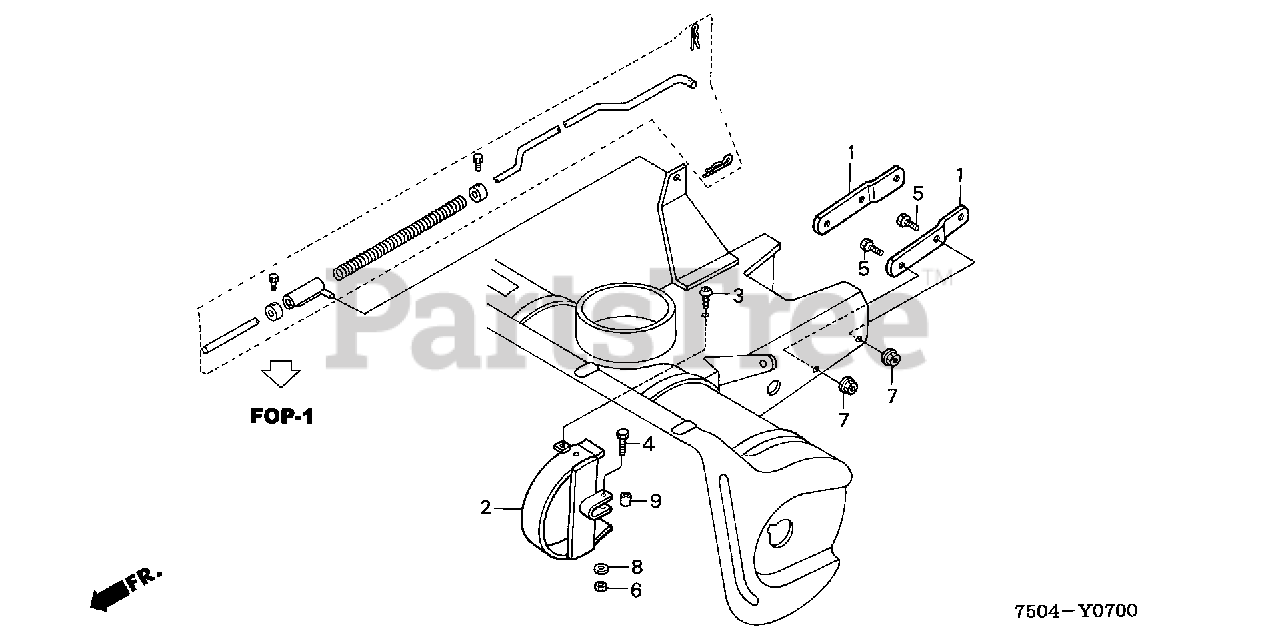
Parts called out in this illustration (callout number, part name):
1	CLIP, FRAME
2	GUARD ASSY., BELT
3	SCREW, SELF-TAPPING (5/16)
4	BOLT, HEX. (5/16-18X1 3/4)
5	BOLT, HEX. (7/16-14X1)
6	NUT, HEX. (5/16-18)
7	NUT, LOCK FLANGE (7/16-14)
8	WASHER, LOCK (5/16)
